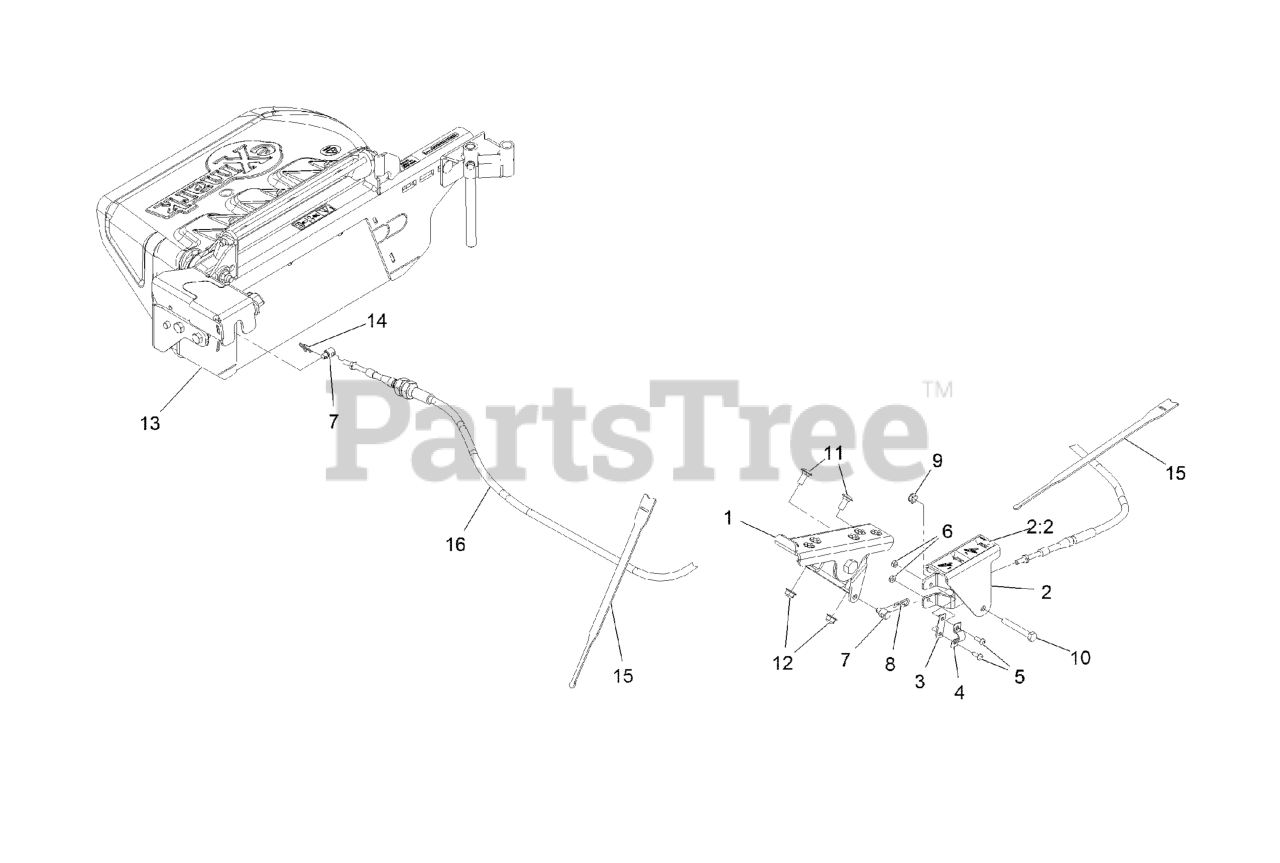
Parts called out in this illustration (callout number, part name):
1	ASM, PEDAL, OCD GATE
2	ASSEMBLY, CABLE BRACKET
2:2	DECAL-OCD OPERATION
3	SHIM,CONTROL CABLE
5	SCREW-PPH
6	NUT-LOCK, NI
7	PIVOT, CONTROL CABLE
8	PIN-COTTER
9	NUT-LOCK, NI
10	SCREW-HH
11	SCREW-CARR
12	NUT-HF, NI
13	ASM, OCD
14	PIN-COTTER, LOCKING
15	STRAP-VELCRO, CABLE TIE
16	CABLE-DISCHARGE GATE
